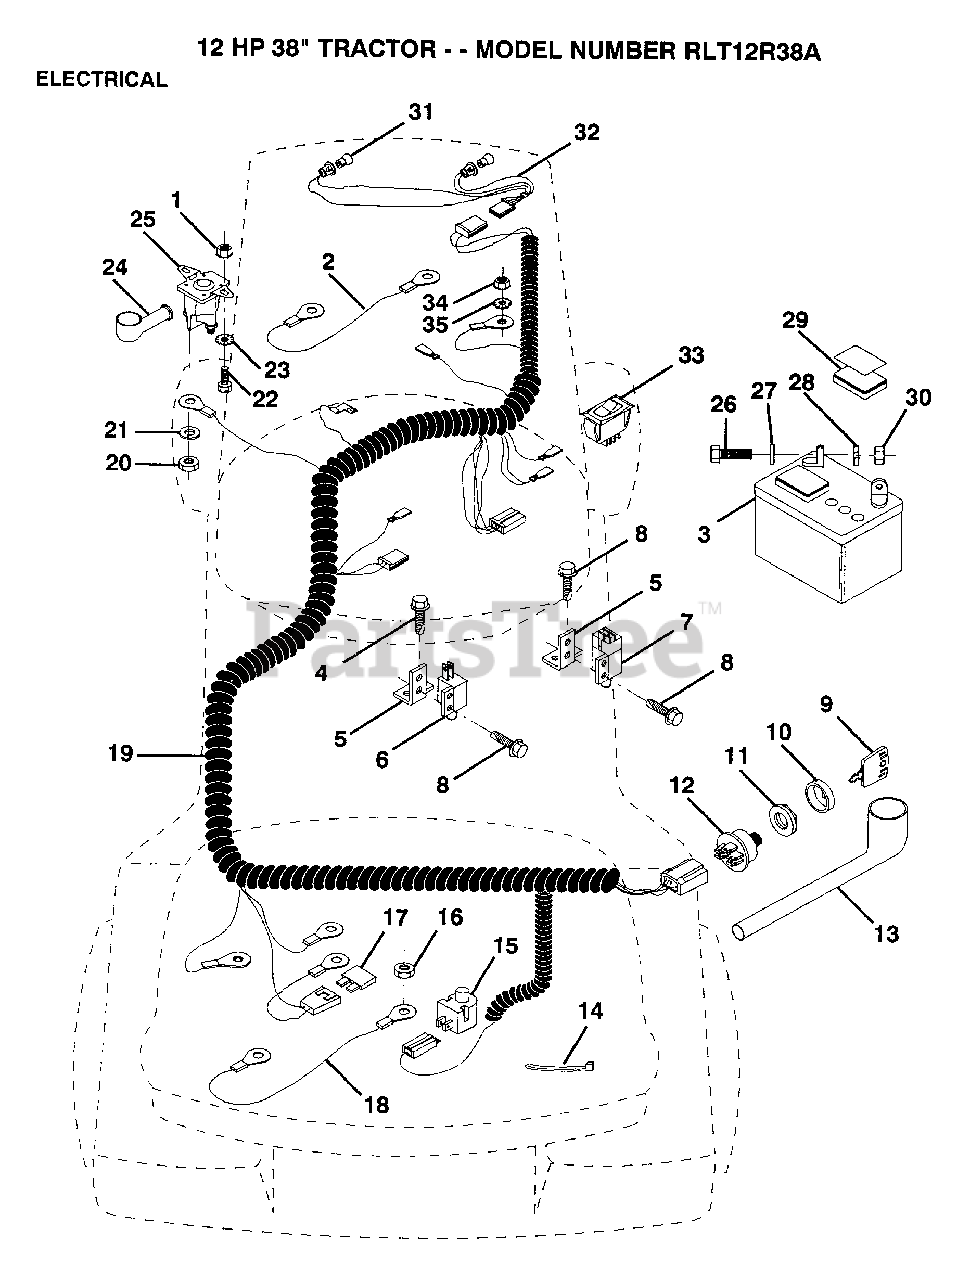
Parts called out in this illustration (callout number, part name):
1	NUT
2	CABLE ASM.
4	SCREW
5	BRACKET LT
6	SWITCH-INTER. GT
7	SWITCH INTERLOCKT
8	SCREW
9	KEY
11	NUT IGNITION
13	COVER IGNITION SW
14	WIRE TIE
15	SWITCH SEAT
17	FUSE HYT
18	CABLE ASSY
19	"HARNESS,IGNITION"
20	NUT
22	BOLT
26	BOLT LT
27	WASHER
28	LOCKWASHER
29	"CAP,BATTERY "
33	SWITCH LT
34	NUT
35	LOCKWASHER
